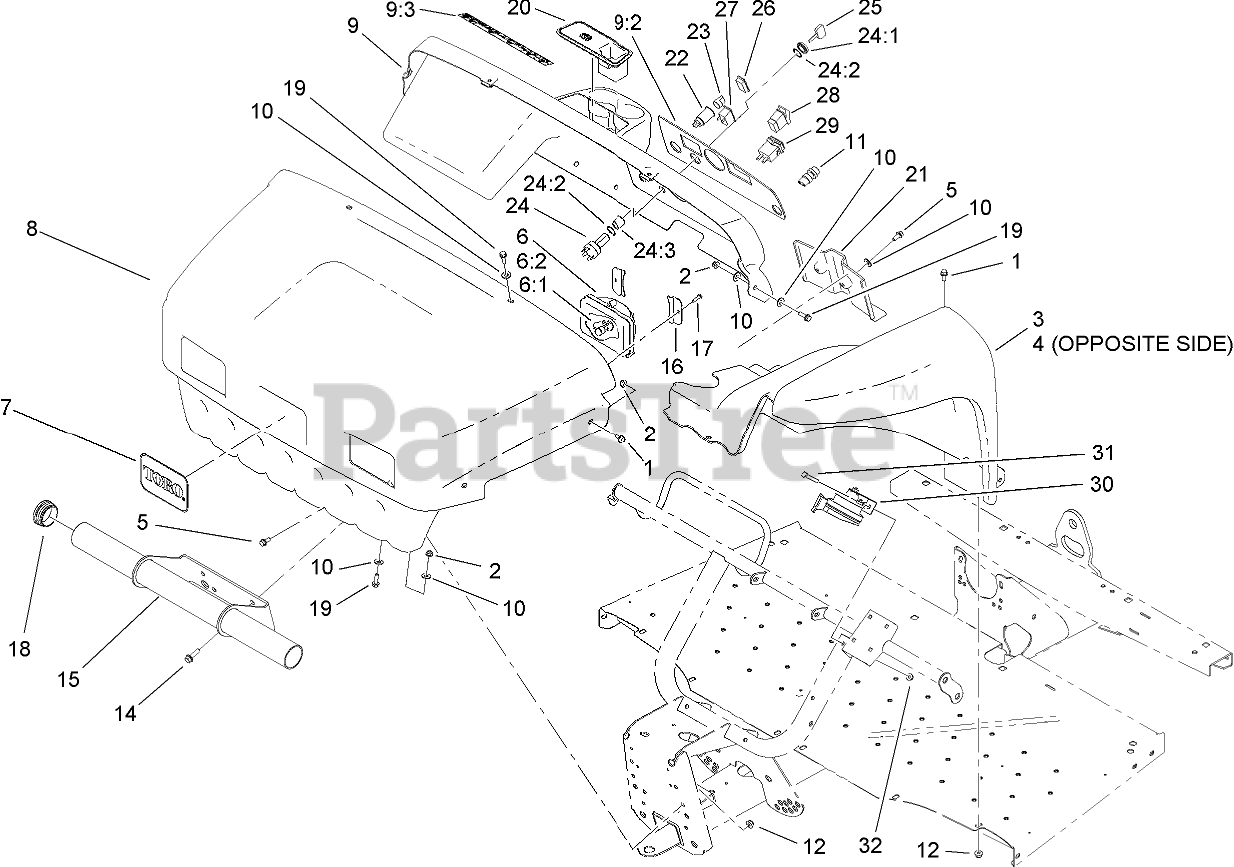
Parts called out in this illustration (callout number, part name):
1	SCREW-HHF
2	NUT-HF, NI
3	LH FENDER ASM
4	RH FENDER ASM
5	SCREW-HHF
6	HEADLIGHT
6:1	LAMP-12 VOLT
6:2	LENS-HEADLIGHT
7	DECAL
8	HOOD ASM
9	DASH ASM
9:2	DECAL-WARNING
9:3	DECAL-DANGER
10	WASHER-FLAT
11	BUTTON-HORN
12	NUT-HF, NI
15	BUMPER-TUBE
16	BRACKET-HEADLIGHT
17	SCREW-HWH
18	CAP-END
19	SCREW-HHF
20	PLUG-RUBBER
21	COVER-CHANNEL
22	POINT-POWER
24	Switch-Ignition
24:1	NUT-SWITCH, PLASTIC
24:2	WASHER-LOCK, INTERNAL
24:3	SPACER-SWITCH
25	KEY-IGNITION
26	PLUG-HOLE
27	INDICATOR-LIGHT, LOW-OIL PRESSURE
28	SWITCH
29	HOURMETER
31	SCREW-HH
32	NUT-HF, NI
